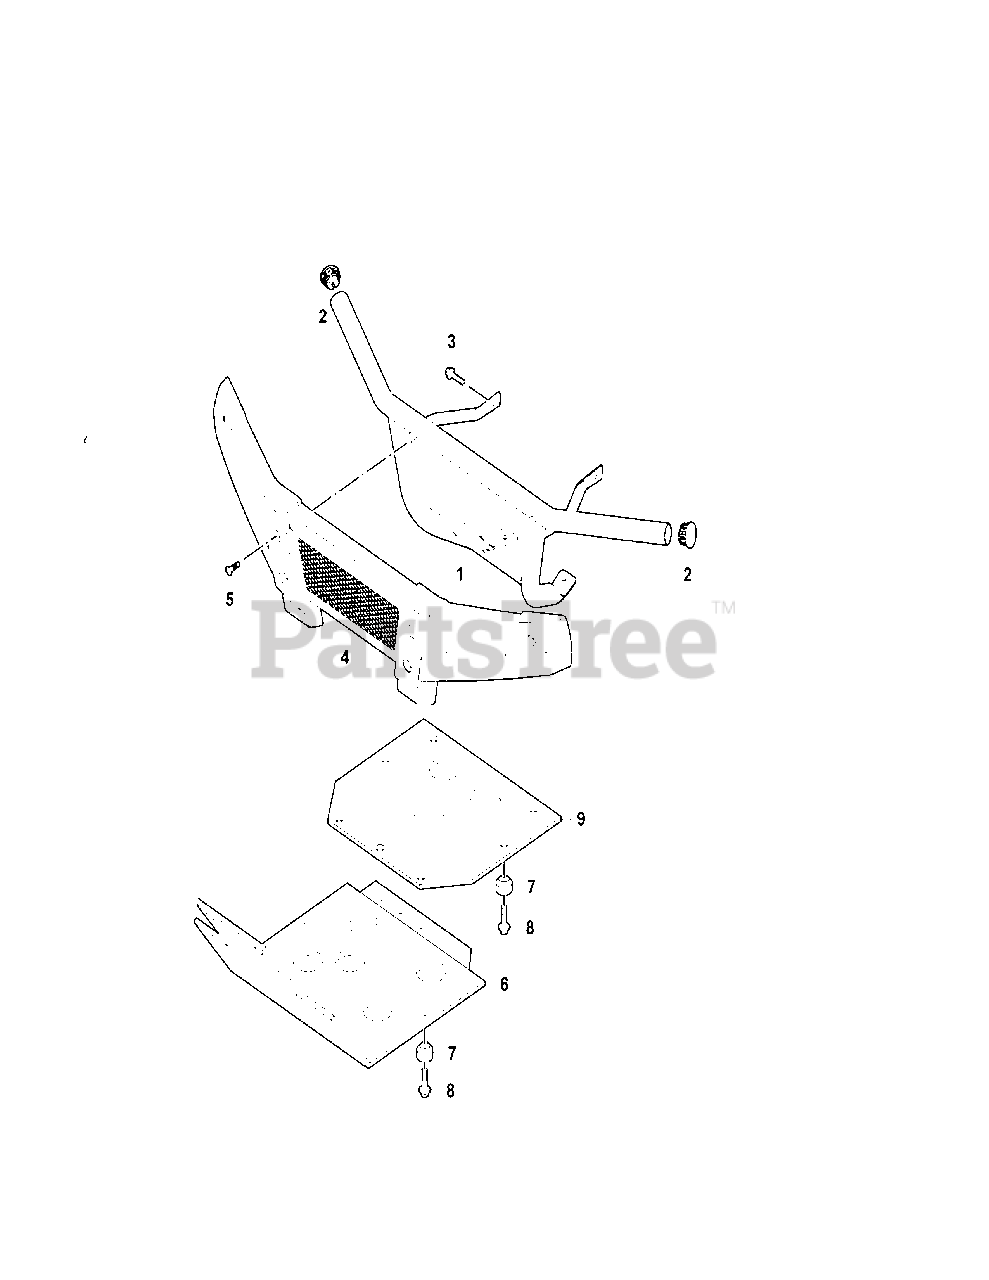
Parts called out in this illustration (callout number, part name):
1	Front Bumper
2	Bumper Pipe Plug I
3	Hexagon flange bolt M10×1.25×20
4	Protective Cover,Front Bumper
5	Cross large plate head screw M6×16
6	Protective plate, front bumper
7	Cap washer
8	Hexagon Flange Bolt M6×16
9	Rear lower protective plate
